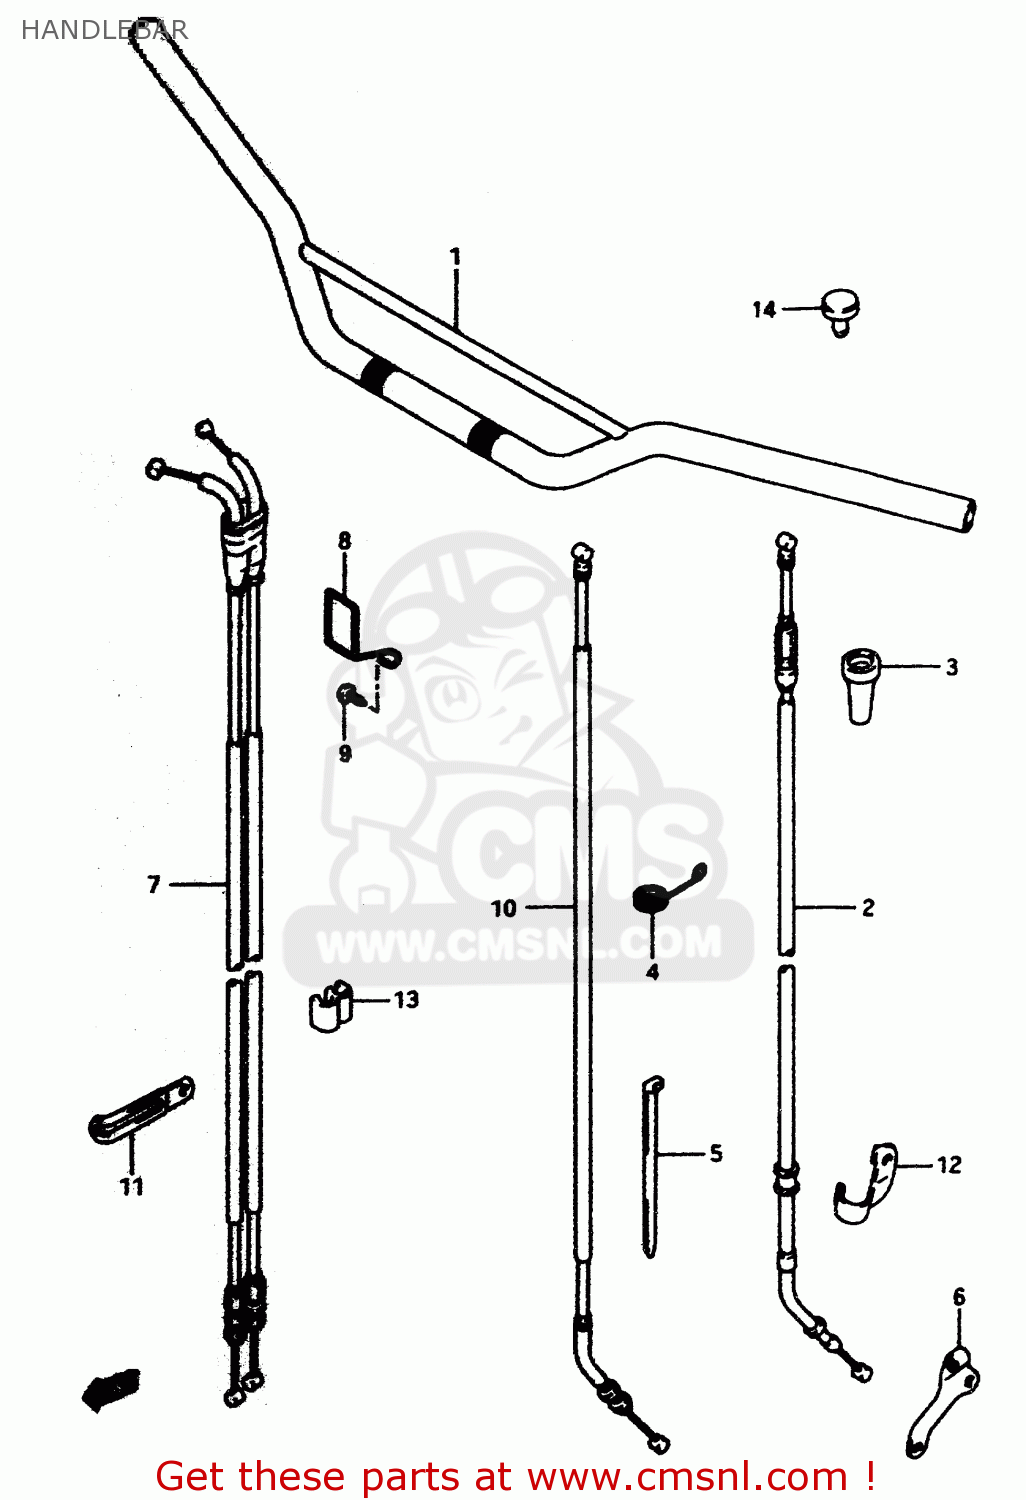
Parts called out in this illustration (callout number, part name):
1	HANDLEBAR(BLACK)
2	CABLE ASSY,CLUTCH
3	BOOT,CLUTCH CABLE
4	GUIDE,CLUTCH CABLE
5	CLAMP(L:145)
6	STOPPER,CLUTCH CABLE
7	CABLE SET,THROTTLE
8	GUIDE,CABLE
9	BOLT
10	CABLE ASSY,DECOMP
11	CLAMP(L:65)
12	CLAMP,CLUTCH CABLE
13	CLIP
